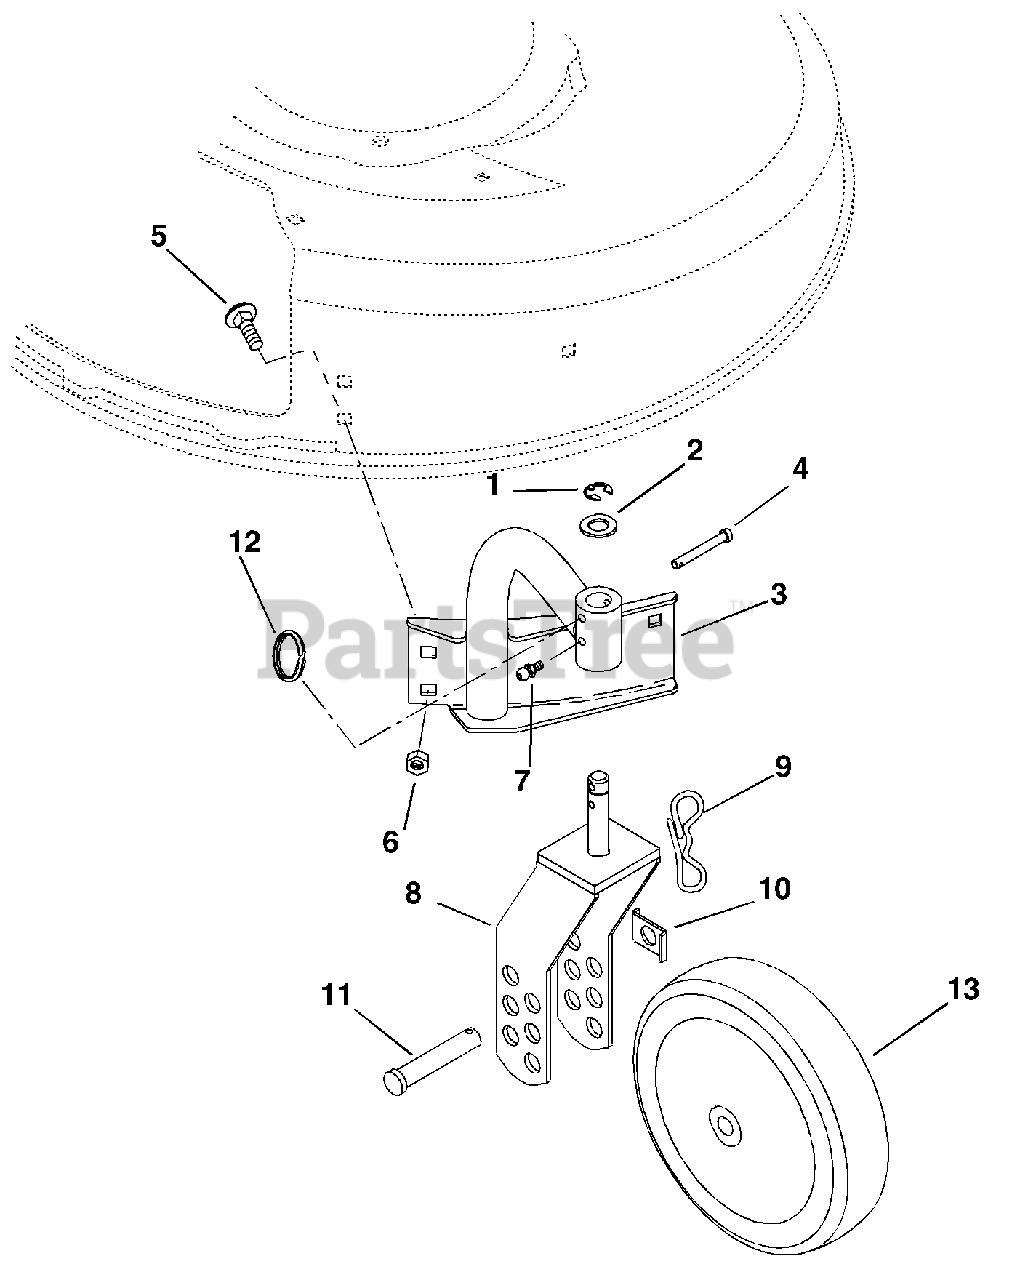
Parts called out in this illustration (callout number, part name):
1	Ring-Retaining-External .625 x .042
2	Washer-Flat-Steels .630 x 1.005 x .062
3	Mount with Bushing, Right Arm
3	Mount with Bushing, Left Arm
4	Pin-Clevis .25 x 1.75
5	Bolt-Round Head Square Neck .31-18 x .50 Grade 5
6	Nut-Hex .312-18
7	Fitting-Lube .25-28 x .256
8	Wheel Yoke Weldment
9	Pin, Bowtie Cotter
11	Pin-Clevis .494 x 2.62
12	Ring-Kickout
13	Wheel-7.50 O.D. Steel Swivel
